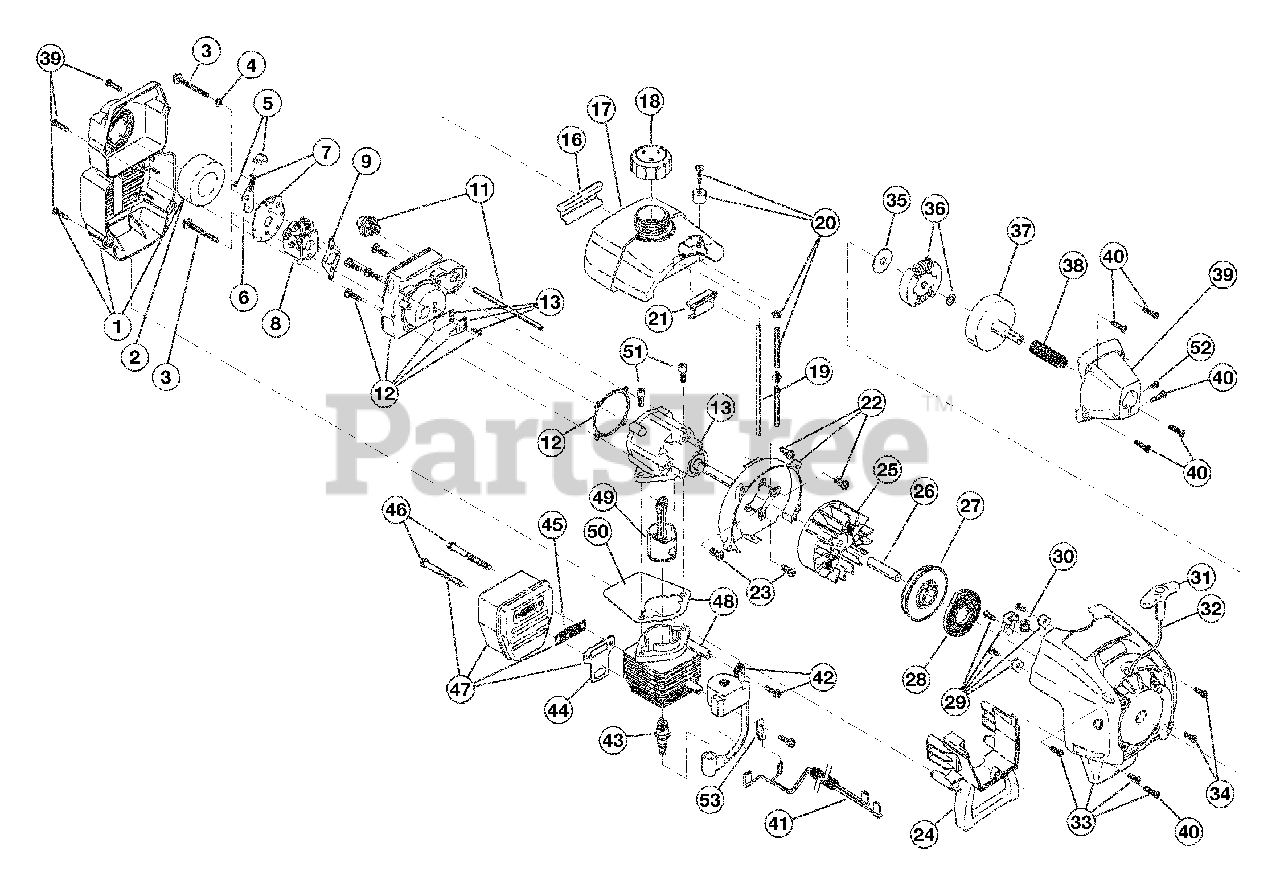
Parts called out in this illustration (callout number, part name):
1	Carburetor/Air Cleaner Cover Assembly
2	Air Cleaner Filter
3	Carburetor Mounting Screw Assembly
4	Wavey Washer
5	Choke Knob & Screw
6	Choke Lever Assembly
7	Choke Plate Assembly
8	Carburetor Assembly
9	Carburetor Gasket
10	Carb Mount Screw
11	Primer and Hose Assembly
12	Carb Mount Assembly
13	Reed Assembly
14	Carburetor Mount Gasket
15	Crank Case Service Assembly
16	Rear Mounting Pad
17	Fuel Tank Assembly
18	Fuel Cap Assembly
19	Fuel Return Line
20	Fuel Line Assembly
21	Front Mounting Pad
22	Shroud Assembly
23	Shroud Screw
24	Shroud Extension & Stand
25	Flywheel Assembly
27	Recoil Pulley Assembly
28	Recoil Spring
29	Pulley Retainer Assembly
30	Rope Guide
31	Pull Handle
33	Starter Housing Assembly
34	Housing Screw
35	Clutch Washer
36	Clutch Rotor Assembly
37	Clutch Drum Assembly
39	Clutch Cover Assembly
40	Cover Screw
41	Wire Lead
42	Module Assembly
43	Spark Plug
44	Exhaust Gasket
45	Spark Arrestor
46	Muffler Mounting Bolt Assembly
47	Muffler Assembly
48	Cylinder Assembly
49	Piston and Rod Assembly
50	Cylinder Gasket
51	Cylinder Bolt
52	Anti-Rotation Screw
53	Ground Tab
